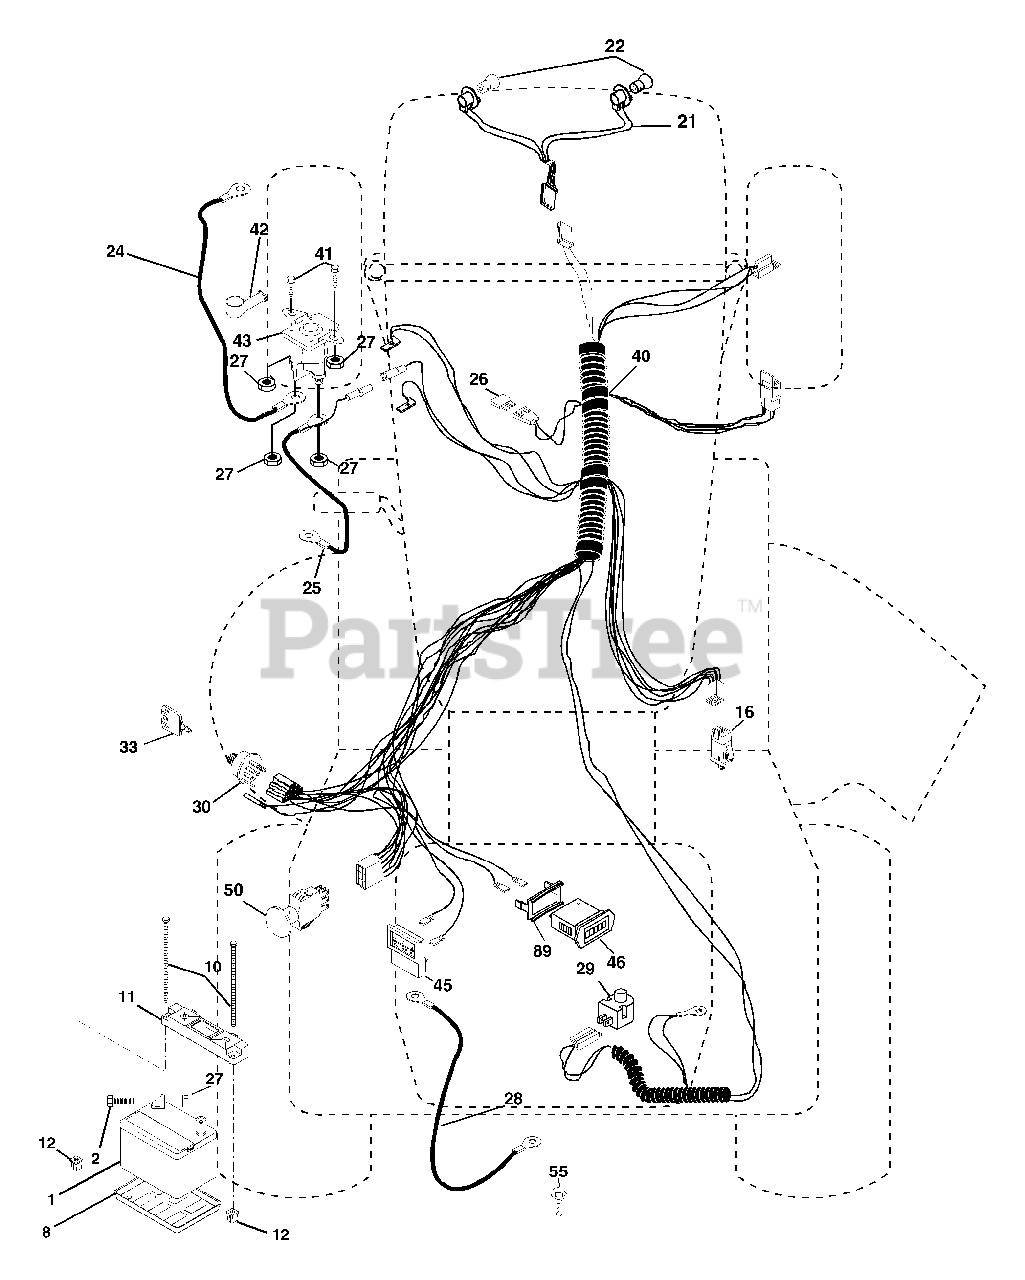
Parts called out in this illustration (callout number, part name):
1	Battery
2	Bolt Hex Hd 1/4-20 unc x 3/4
8	Battery Tray
10	Bolt 1/4-20 x 7.5
11	Holddown Battery Front Mount
12	Nut Push Nylon 1/4"
16	Switch Interlock Push-In
21	Harness Asm Light W/4152j
22	Bulb Light #1156
24	Cable Battery 6 Ga. 11" red
25	Cable Battery 6 Ga. 22" red w/16 wire
26	Fuse 20 AMP
27	Nut Keps Hex 1/4-20 unc
28	Cable Ground black
29	Switch Plunger Nc Gray
30	Switch Ign
33	Key Ign Molded Generic
40	Harness Ign.
41	Bolt Blk Fin Hex 1/4 - 20 x 1/2
42	Cover Terminal Red
43	Solenoid
46	Hourmeter Snap-In
50	Switch PTO
55	Screw 5/16-18 x 1/2
89	Bracket Snap-In Hourmeter
